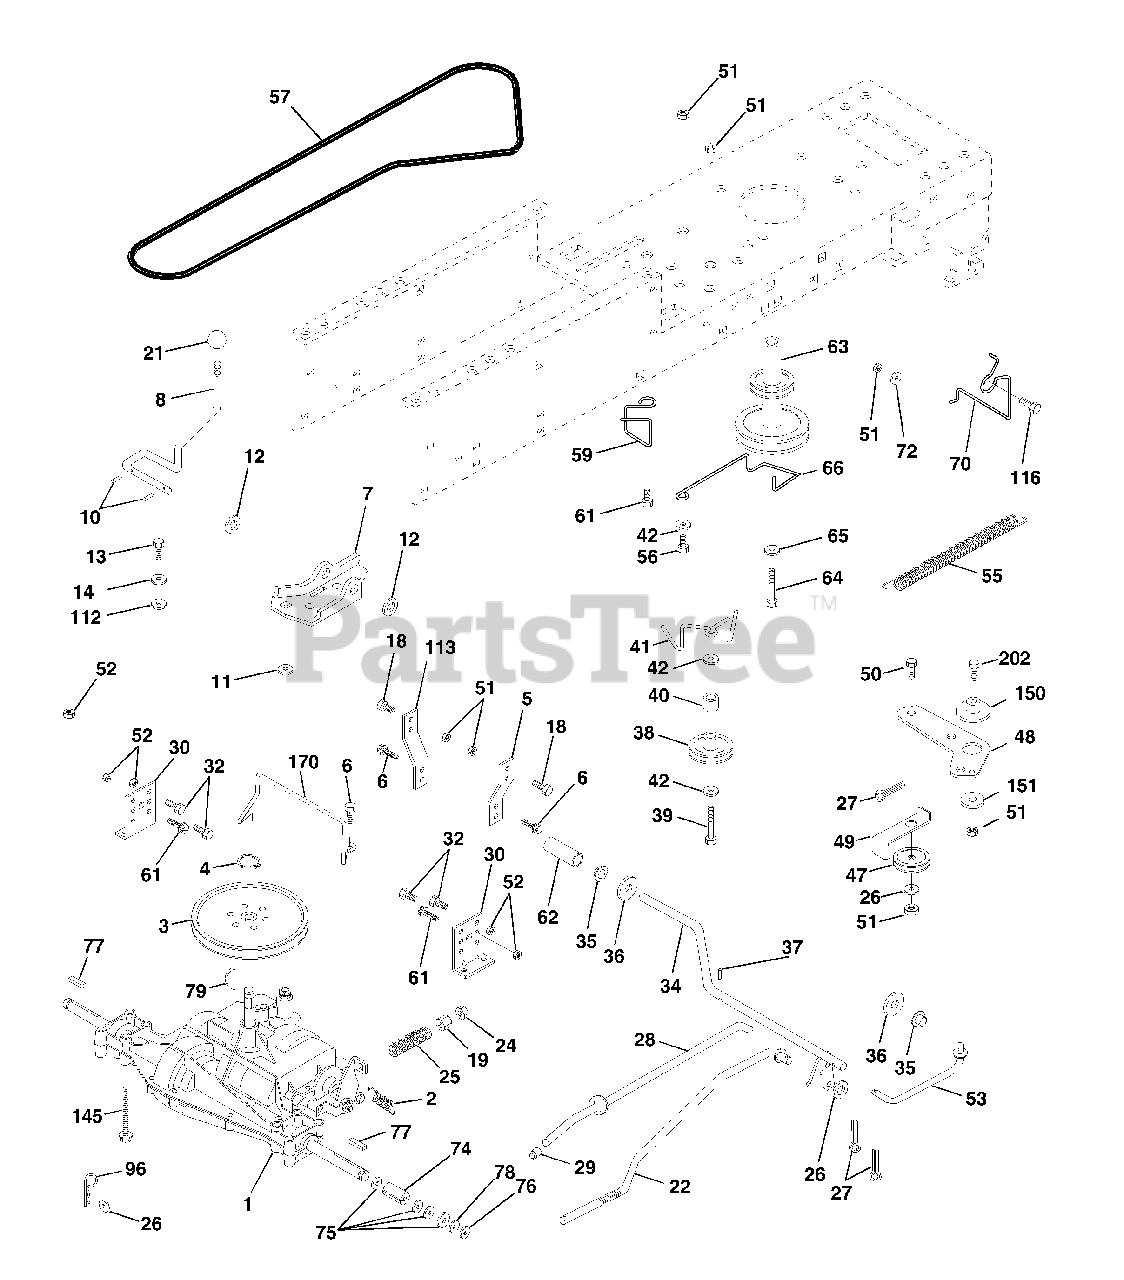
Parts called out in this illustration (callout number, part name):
2	Spring Extension Brake
3	Pulley Transaxle 18" tires
4	Ring Retainer # 5100-62
5	Strap Torque Rh Pnt Blk
6	Screw 5/16-18 X 3/4
7	Bracket T/A Saddle Shift
8	Rod Shifter Black(dana)
10	Pin
11	Washer Plate Shf 388 Sq Hole
12	Washer 15/32 X 3/4 X 16ga
13	Bolt 1/4-28 UNF Gr. 8 W/Patch
14	Washer
18	Bolt Fin Hex 3/8-16 UNC x 1 Gr. 5
19	Nut
21	Knob Rd 1/2-13 Plstc Thds Blk
22	Rod Brake Lt
24	Nut
25	Spring Rod Brake 2 00 Zinc
26	Washer
27	Pin
28	Rod Brake Parking Lt/Yt
29	Cap Parking Brake
30	Bracket Transmission
32	Bolt
34	Shaft Asm Pedal Foot
35	Bearing Nylon Blk 629 Id
36	Washer
37	Roll Pin
38	Pulley Idler Flat
39	Bolt Fin Hex 3/8-16 Unc x 2-3/4
40	Spacer Split 395 X 59 Bzp
41	Keeper Belt Idler
42	Washer 13/32 X 13/16 X 12 Ga
47	Pulley Idler V Groove Plastic
48	Bellcrank Clutch
49	Retainer Belt Style Spring
50	Bolt
51	Nut
52	Nut
53	Link Clutch 7 66
55	Spring Return Clutch 6 75
56	Bolt
57	V-belt Ground Drive 95
59	Keeper Belt Chassis Span Ctr.
61	Screw 3/8-16x3/4
62	Cover Pedal Blk Round
63	Pulley Engine
64	Bolt, Hex 7/16-20 x 4 Grade 5
65	Washer, Lock, Hvy Hlcl Spring 7/16
66	Keeper Belt Engine Flproof
70	Guide Belt Dr Mower Rh
72	Washer 13/32 X 1-1/4 X 12 Ga
74	Spacer Axle
75	Washer 25/32 X 1 1/4 X 16 Ga
76	E Ring
77	Key Square 2 0 X 1845/ 1865
78	Washer 25/32 X 1 5/8 X 16ga
79	Key Woodruff
96	Retainer Spring 1"
112	Washer 9/32 X 3/4 X 10 Ga
113	Strap Torque Lh
116	Bolt, Rdhd Sqnk 3/8-16 x 1.25
145	Bolt Hex Flghd 5/16-18 x Gr. 5
150	Bushing Bellcrank
151	Washer 13/32 x 2 x 10 Ga.
170	Keeper Belt
202	Bolt Carr. Sh. 3/8-16 x 1-1/2 Gr. 5
